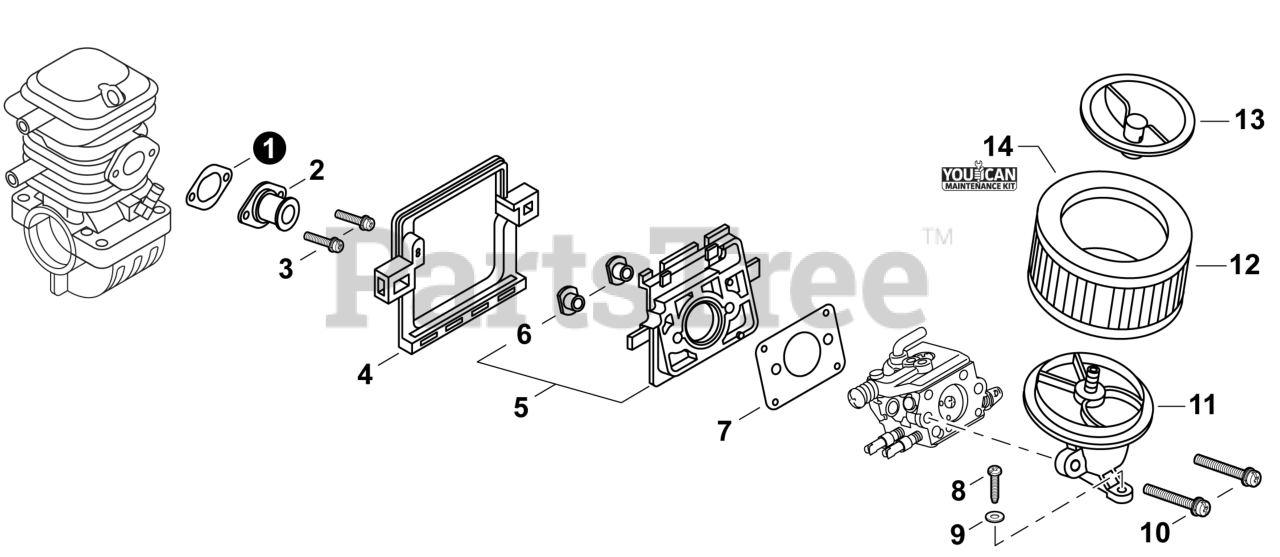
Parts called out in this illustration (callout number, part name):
1	GASKET, INTAKE
2	BELLOWS, INTAKE
3	SCREW 5x14
4	CUSHION
5	INSULATOR KIT, INTAKE
7	GASKET, INTAKE
8	SCREW, TAPPING 5x20
9	WASHER, FLAT 5.5x10x0.8
10	SCREW 5x50
11	ADAPTOR, INTAKE
12	FILTER, AIR - HEAVY DUTY
13	CAP, AIR FILTER
14	TUNE-UP KIT - YOUCANT
